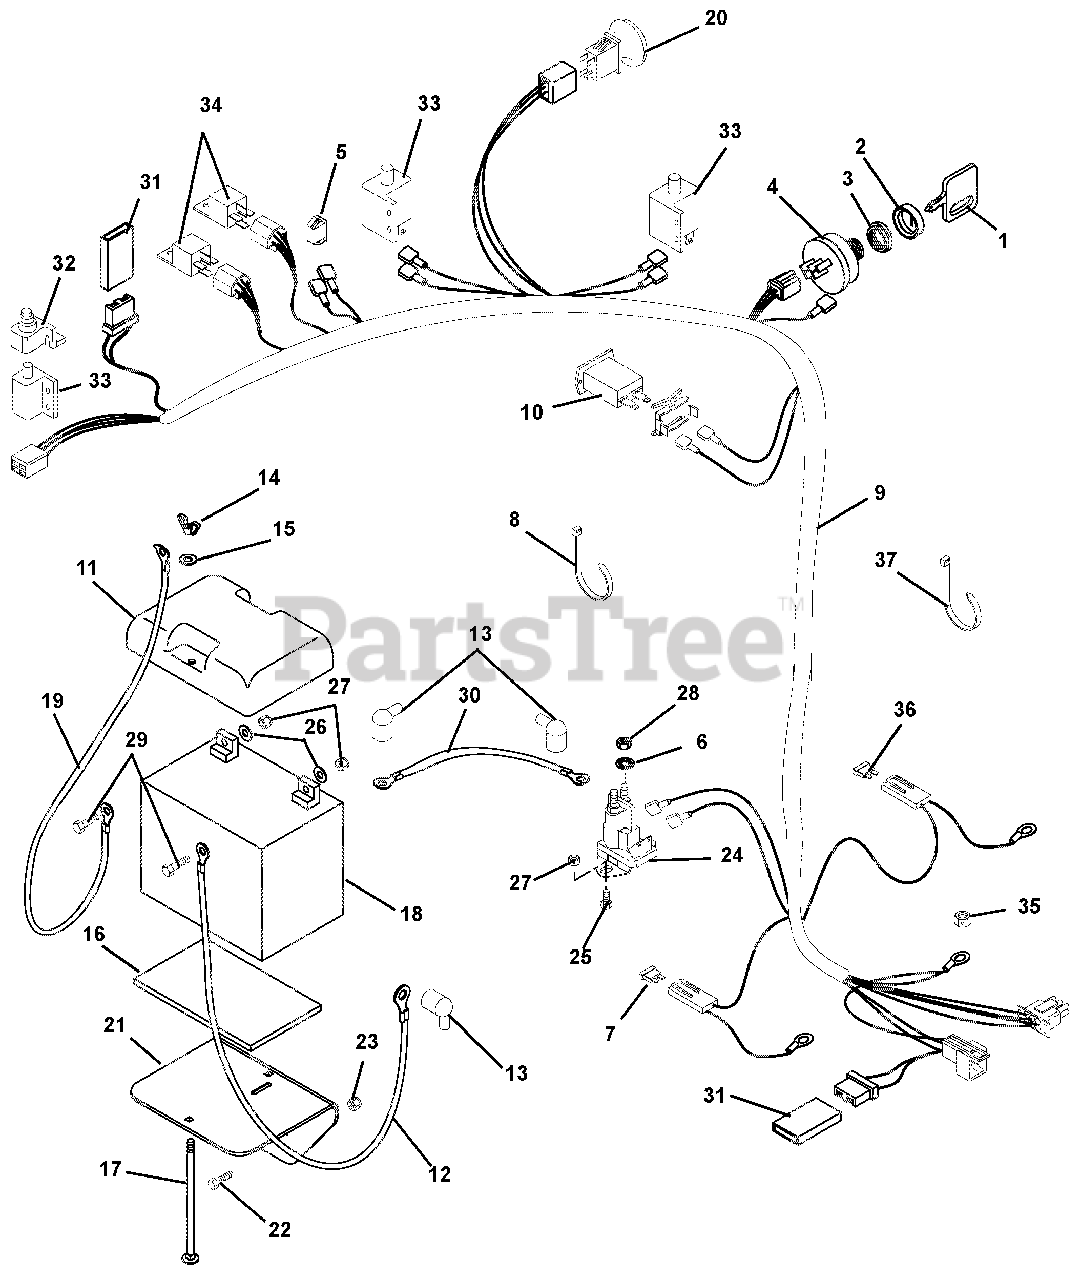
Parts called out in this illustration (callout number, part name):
1	Key- with Cap
2	Cap, Ignition Switch
3	Nut, Panel .625-32
4	Key Switch
5	Light, Indicator
6	Washer-Locking .31
7	Fuse-25 AMP
8	Tie Wrap-Black
9	Wire Harness
10	Hour Meter-Quartz
11	Cover-Battery
12	Cable, Positive Battery
13	Boot, Eyelet Terminal
14	Nut-Locking-Wing .25-20
15	Washer-Flat-Steel .281 x .625 x .065
16	Pad, Battery
17	Bolt-Round Head Square Neck .25-20 x 7.00 Grade 2
18	Battery, Filled
19	Cable, Negative Battery
20	Switch- PTO- NMIR
21	Weldment, Battery Tray
22	Bolt-Hex .38-16 x 1.75 Grade 5
23	Nut-Locking-Nylon .38-16
24	Solenoid
25	Bolt-Hex .25-20 x .50 Grade 5
26	Washer-Flat-Steel .281 x .62 x .065
27	Nut-Locking-Flange .25-20 (108, 109)
28	Nut- Jam .31-24
29	Bolt-Hex .25-20 x .75 Grade 5
30	Starter Cable 6.75"
31	Diode, Connector Shell
32	Boot, Rubber
33	Switch, Interlock
34	Relay
35	Nut-Locking-Top-Flange .31-18
36	Fuse-20 AMP
37	Tie Wrap
